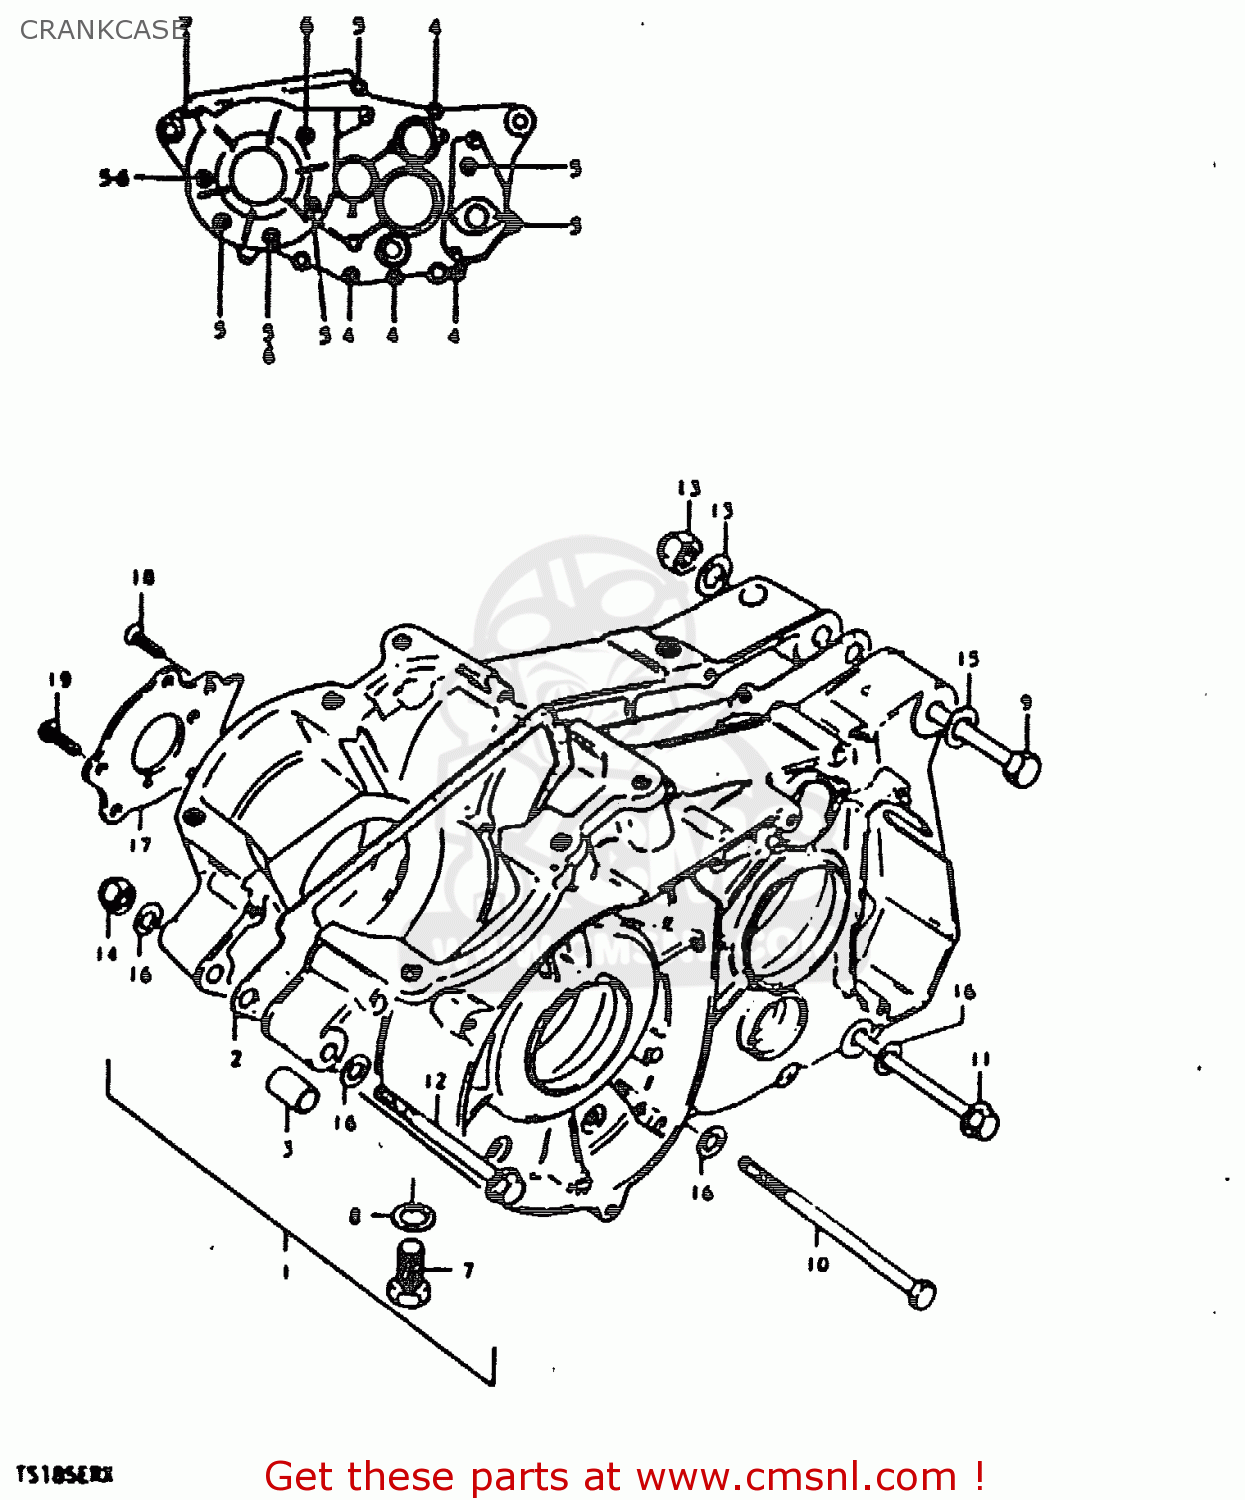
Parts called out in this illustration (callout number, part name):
1	CRANKCASE SET
2	GASKET,CRANKCASE (MCA)
3	PIN
4	SCREW 6X65
5	SCREW (6X45)
6	WASHER 6MM
7	PLUG
8	GASKET(14X19.2X2) (NAS)
9	BOLT
10	BOLT(8X145)
11	BOLT
12	BOLT
13	NUT
14	NUT
15	WASHER
16	WASHER
17	PLATE,OIL RESERVOIR
18	SCREW
19	SCREW
